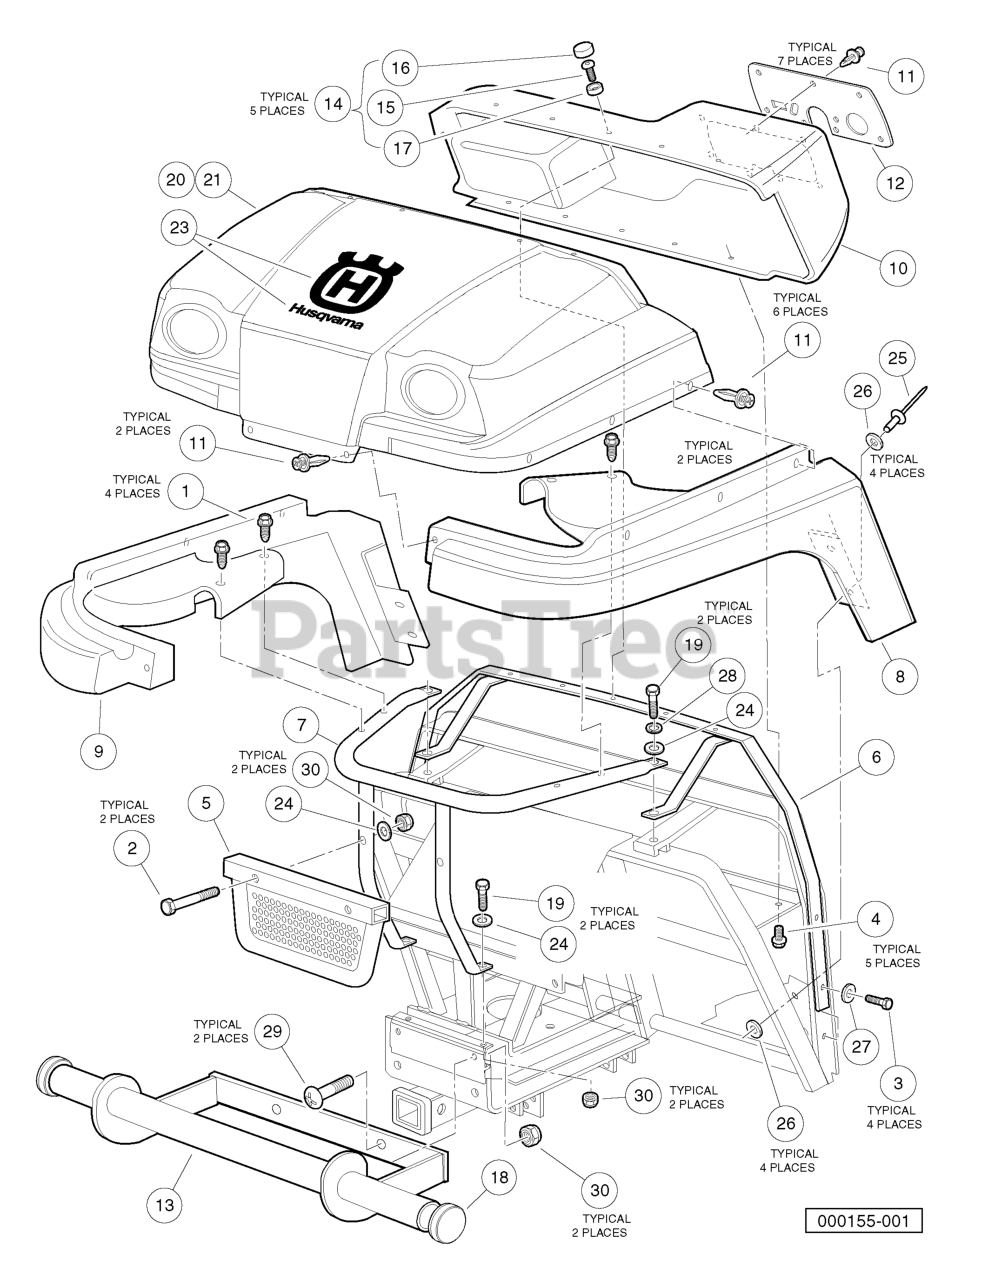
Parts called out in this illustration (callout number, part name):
1	SCREW, HEX WASH
2	SCREW HEX CAP
3	SCREW HX TYP TT
4	SCREW, #12 X .50 TYP AB HX WSH
5	GRILL ASSY
6	SUPPORT, UPPER COWL
7	SUPPORT, LOWER FENDER
8	FENDER, LEFT FRONT
9	FENDER, RIGHT FRONT
10	DASH BOARD
11	PANEL, DASH
12	BUMPER ASSEMBLY
13	KIT - DASH HDWR
14	SCREW 1/4-20X.75 TORX PN HD
15	CAP 1/4" PLASTIC SCREW HEAD
16	WASHER 1/4 ID SCALLOPED PLAST
18	SCREW, 5/16-18 X 2.50 HEX CAP
19	Cowl, Camo
20	COWL, OEM 1299, ORANGE
21	FLOORMAT, MOLDED -UTL
22	DECAL HOOD
23	SCREW, TUFLOK PANEL, 1/4
24	WASHER, 5/16 TYPE A FLAT
25	RIVET, 3/16 X .5 ALUM POP
26	WASHER FLAT
27	WASHER 1/4 FLAT
28	LOCKWASHER, 5/16 SPLIT
29	SCREW 5/16-18 X 1.25 TRUSS HD
30	LOCKNUT, 5/16-18 NYLON INSERT
